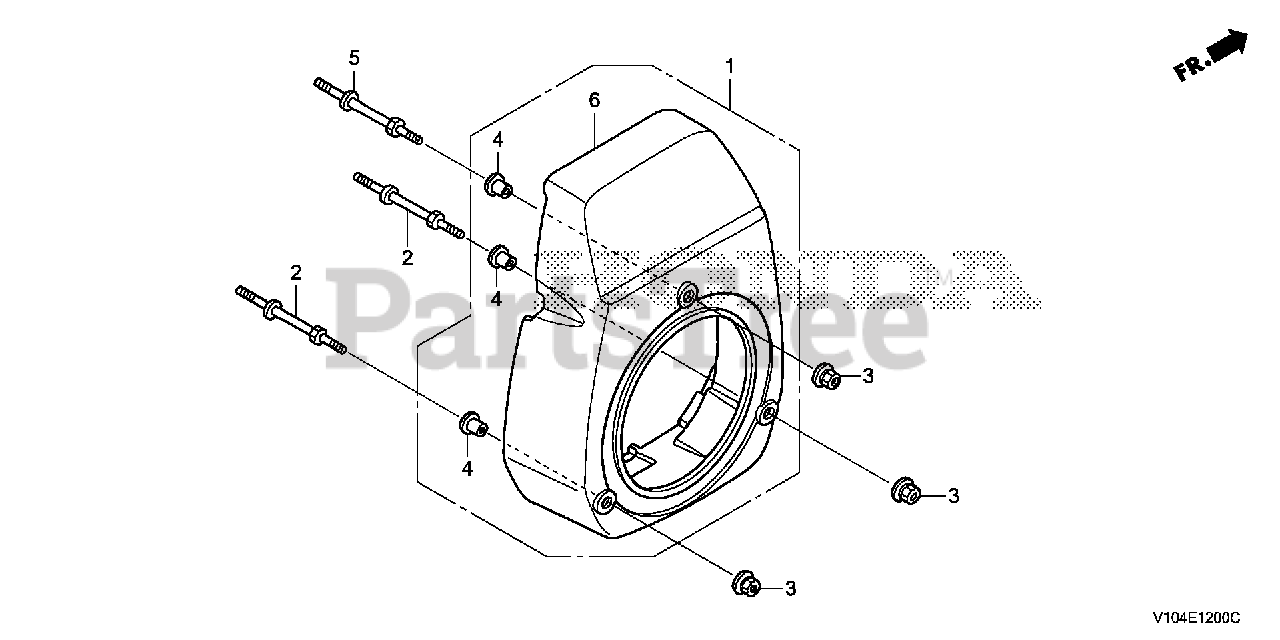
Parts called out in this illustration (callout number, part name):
2	BOLT, STUD (FAN COVER)
3	NUT, FLANGE (6MM)
5	BOLT, STUD (FAN COVER)
6	COVER, FAN *NH1* (BLACK)
